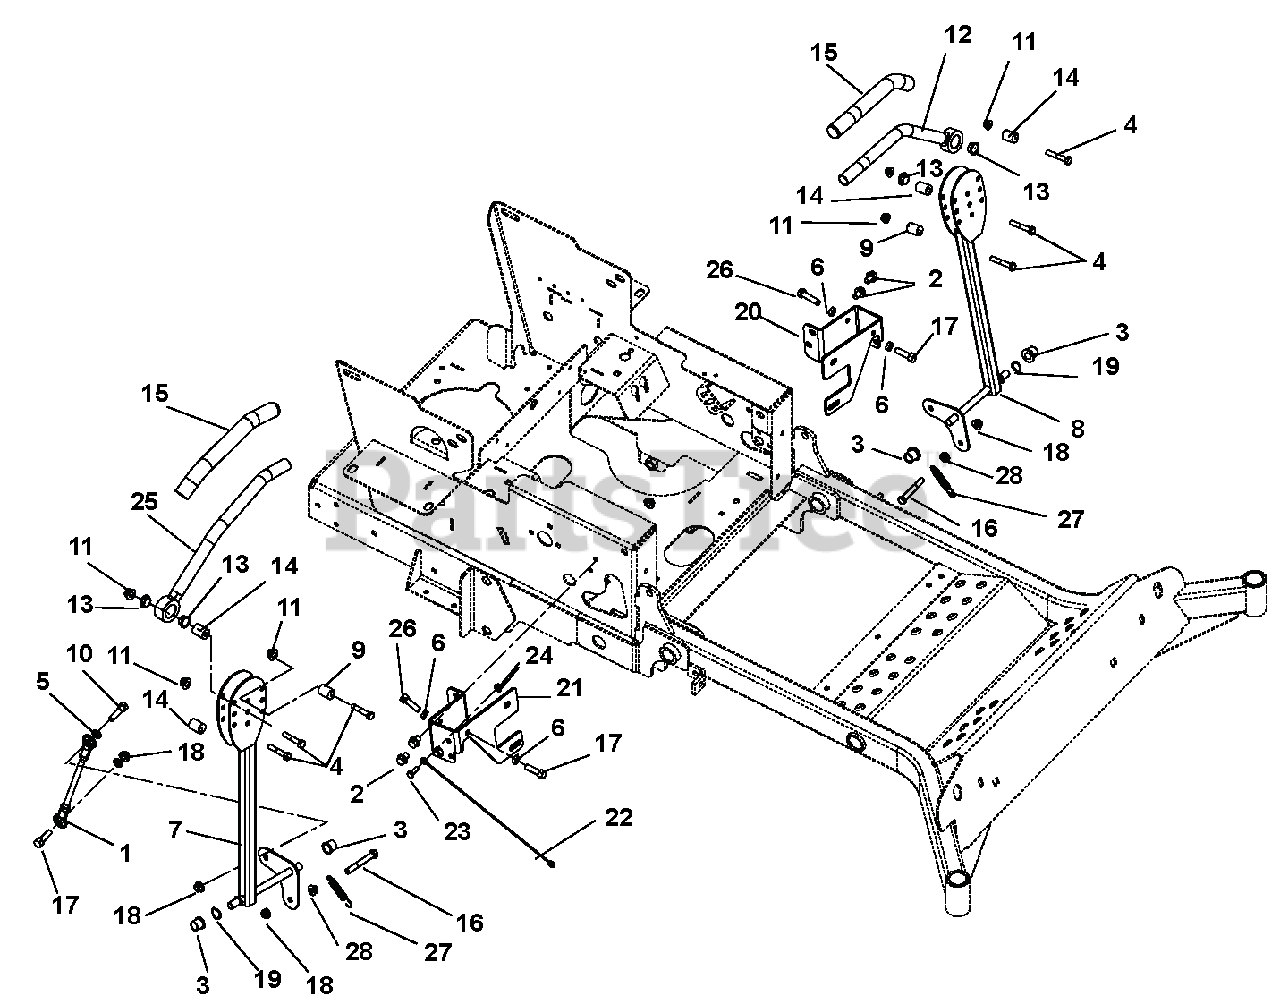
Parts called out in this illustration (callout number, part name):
1	ASM, STEERING LINKAGE
2	@SCR-TAP .38-16X.50 HWH TR YWZ
3	BSHG-FLG .515X.750X.745X1.00NY
4	@BLT-HEX .31-18X1.75 GR5 YWZC
5	@WSHR-LK .38X.094 REG YWZC
6	NUT-HEX-JAM .375-16 YWZC
7	WMT, RH CONTROL
8	WMT, LH CONTROL
9	BSHG, ECCENTRIC .328X.750X.970
10	@BLT-HEX .38-16X1.50 GR5 YWZC
11	@NUT-LK-NYL-FLG .31-18 YWZC
12	HANDLE WLDMT LH
13	BSHG-FLG .762X1.48X.44 NYL
14	SPACER .328 X .76 X 1.01
15	GRIP, HANDLEBAR
16	@BLT-HEX .38-16X2.75 GR5 YWZC
17	@BLT-HEX .38-16X1.25 GR5 YWZC
18	@NUT-LK-NYL-FLG .38-16 YWZC
19	WAVE WASHER .640X.875X.125FH
20	BRKT, LH STEERING STOP
21	RH STEERING STOP BRKT - BLK
22	CABLE, 12.0 LANYARD, NYLON
23	@BLT-HEX .25-20X.75 GR5 YWZC
24	@NUT-LK-NYL-FLG .25-20 YWZC
25	WLDMT, RH HANDLE
26	@BLT-HEX .38-16X.75 GR5 YWZC
27	SPRING,EXT,.061X.50X3.0
28	@NUT-SPNLK-FLG .375-16 YWZC
